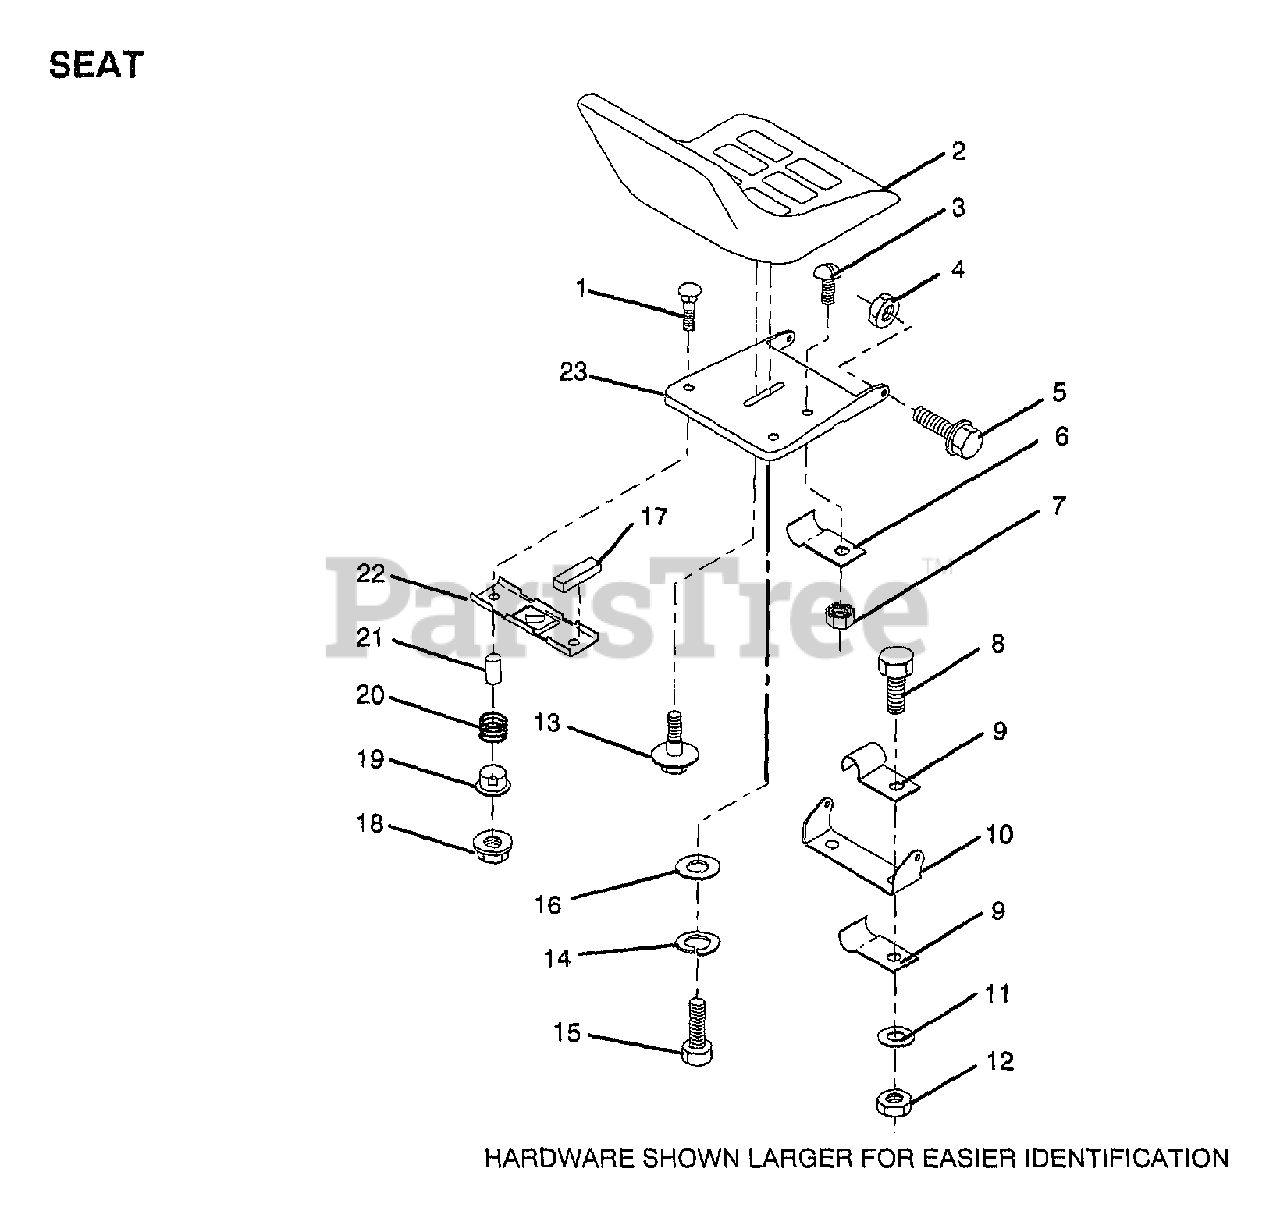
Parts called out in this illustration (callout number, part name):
1	BOLT
7	"NUT,KEPS"
9	"CLIP,INSULATOR"
11	WASHER
13	"BOLT,SHOULDER"
14	LOCKWASHER
15	BOLT
16	WASHER
17	STRIP FORM
19	BUSHING
20	SPRING
21	SPACER SPLIT
22	BRKT SWITCH
